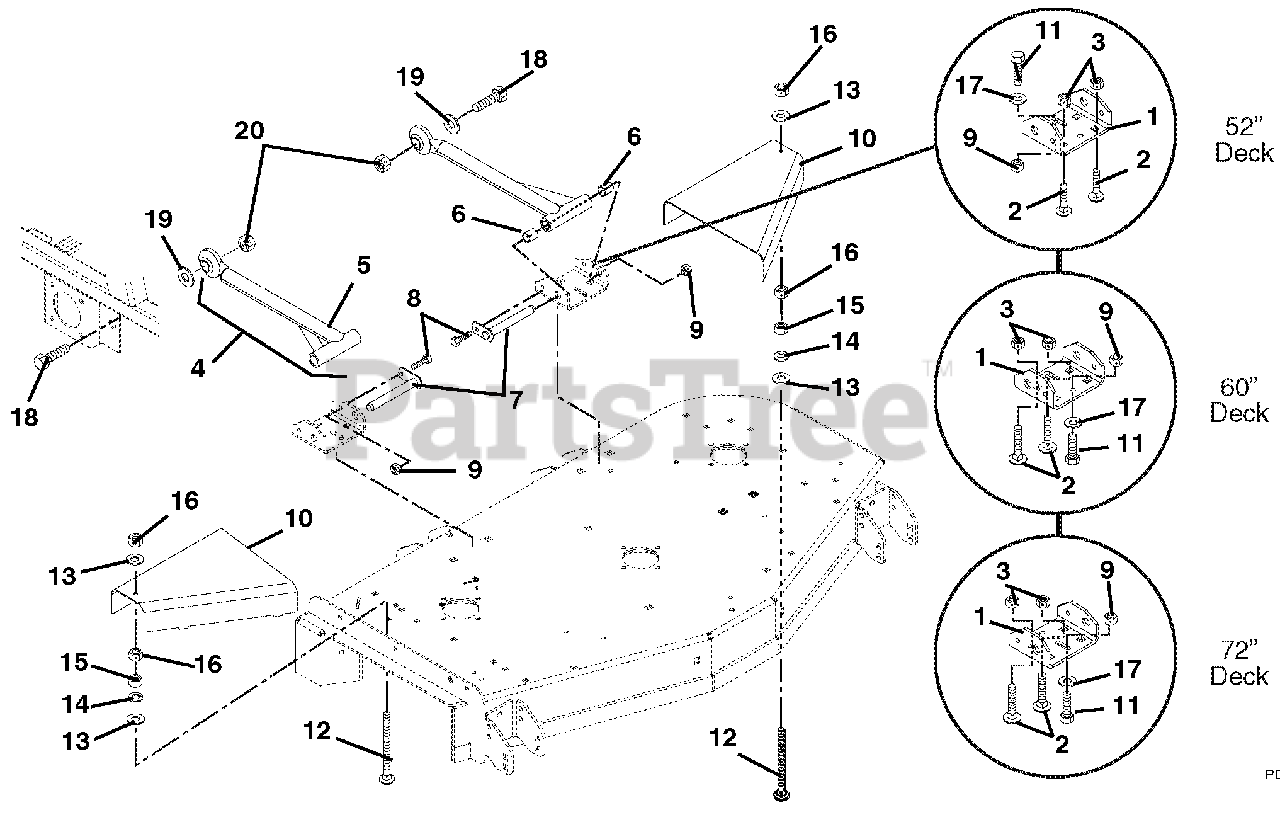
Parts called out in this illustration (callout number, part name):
1	Bracket, Mower Mounting (Rear)
2	Bolt, Round Head Square Neck .50-13 x 1.00 Grade 5
3	Nut, Locking Center Jam .50-13
4	Assembly, Mower Mounting Arm (Includes Items 5 and 6)
5	Weldment, Mower Mounting Arm
6	Bearing .75 x .875 x 1.00
7	Weldment, Mower Mounting Pin
8	Bolt, Hex .38-16 x .75 Grade 5
9	Nut, Locking Top Flange .38-16
10	Guard, Pulley Right Hand (045, 052)
11	Bolt, Hex .38-16 x 1.00 Grade 5
12	Bolt, Round Head Square Neck .31-18 x 3.50 Grade 5 (045, 052)
13	Washer, Flat Steel .344 x .688 x .065 (045, 052)
14	Washer, Locking .31 x .078 (045, 052)
15	Nut, Hex .31-18 (045, 052)
16	Nut, Locking Center .31-18 (045, 052)
17	Washer, Flat Steel .406 x .812 x .065
18	Bolt, Hex .875-9 x 2.75 Grade 5
19	Washer, Flat Steel .875 x 1.50 x .120
20	Nut, Locking Center .875-9
